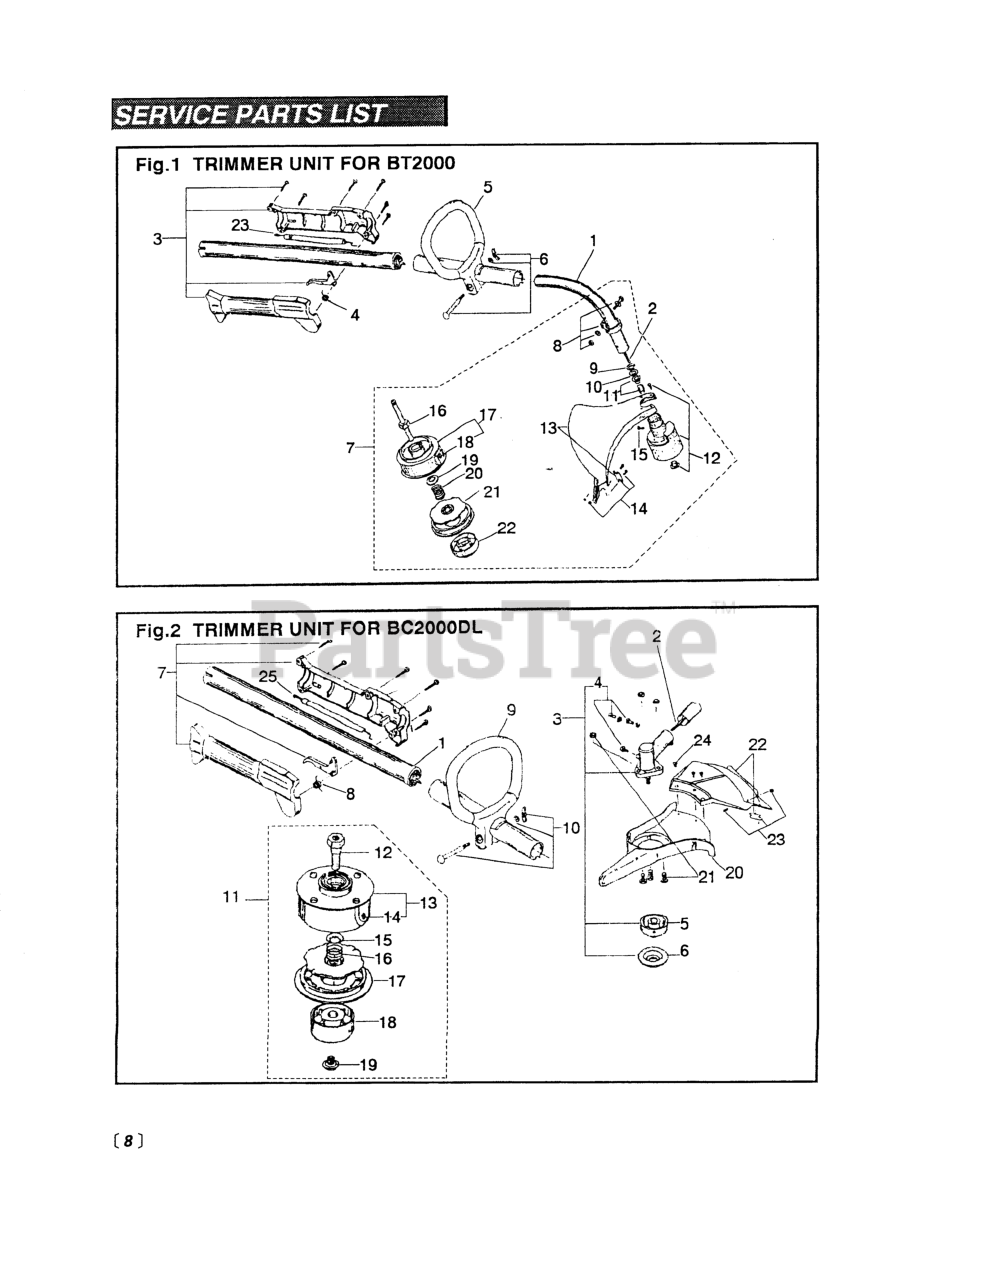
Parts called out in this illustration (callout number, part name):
1	DRIVE SHAFT HSG ASSY (BC)
3	GEARCASE ASSEMBLY
4	HARDWARE, MOUNTING
5	HOLDER (U), BLADE DRIVER
6	HOLDER (L) (RPLS 613222)
8	SPRING, THROTTLE TRIGGER
11	UBT200 - CUTTING HEAD ASSY.
12	SHAFT
13	HOUSING, OUTER SPOOL
14	EYELET
15	WASHER
16	SPRING, INNER REEL
17	REEL, INNER
18	KNOB (USE 180814)
19	KNOB, BUMP HEAD (USE 180814)
20	MOUNT, GUARD
21	GUARD MOUNT HDWE SET
22	GUARD ASSEMBLY
23	BLADE ASSEMBLY
24	SCREW, GUARD MOUNT ASSY
